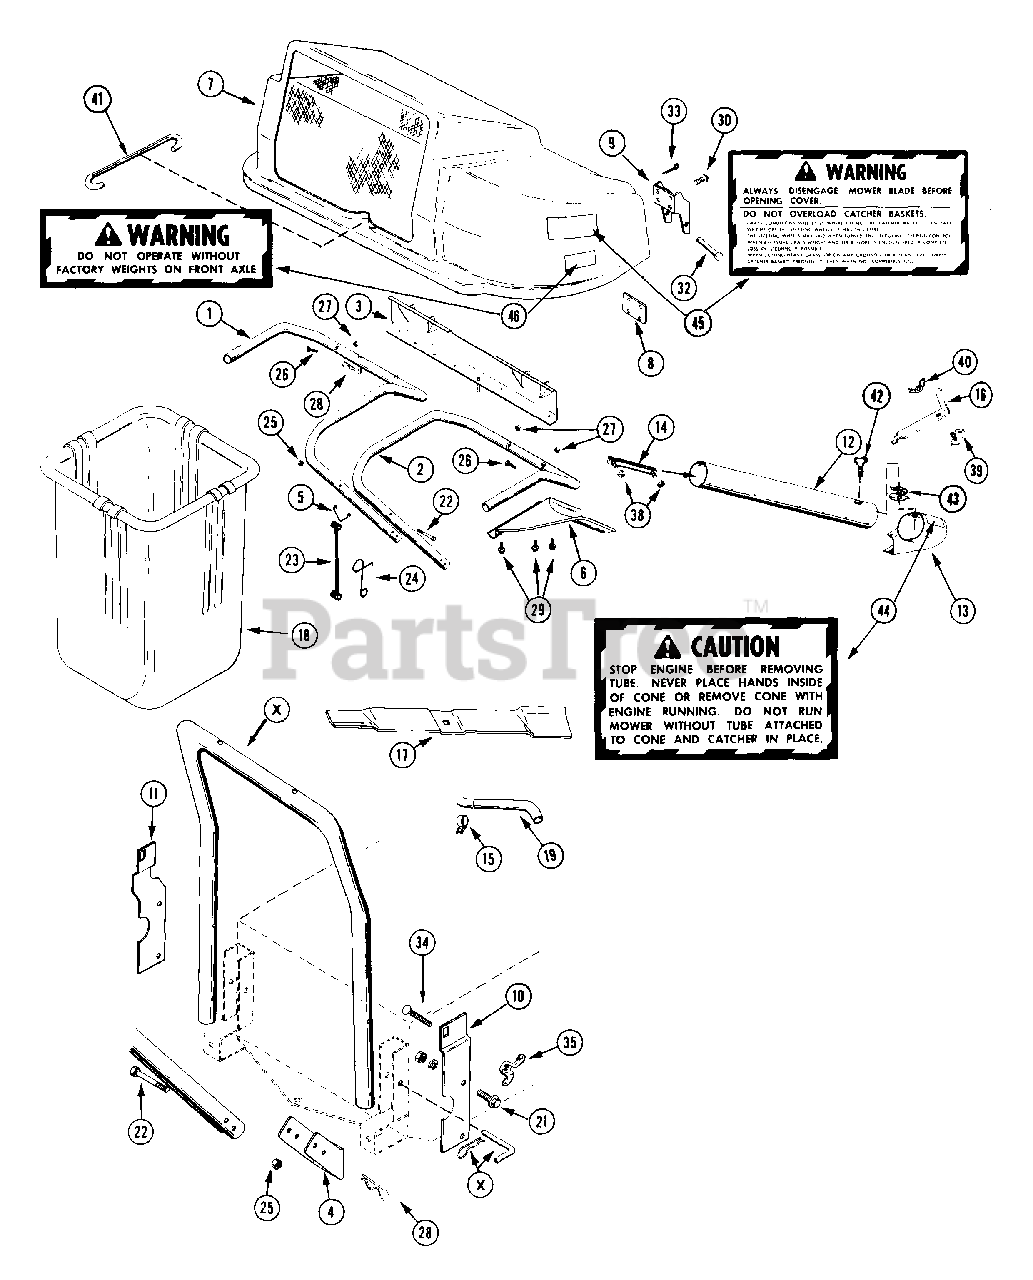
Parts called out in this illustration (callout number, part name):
1	TUBE L.H. SUPPORT
2	TUBE R.H. SUPPORT
3	FRAME-TUBE
4	BRACKET-MOUNTING
6	SUPPORT TUBE
7	GRASS CATCHER COVER ASSEMBLY
8	PLATE REINFORCEMENT
10	STABILIZER R.H.
11	STABILIZER L.H.
12	TUBE BLANK
13	GRASS CATCHER CONE ASSEMBLY
16	STRAP CONE
17	MOWER BLADE
19	EXHAUST PIPE EXTENSION
21	BLT-SERHFWH .31-18X.50 PL
22	BLT-HEX .25-20X2.50 PL GR2
23	BATTERY STRAP
24	HOOK
25	NUT-LK-CTR .250-20 PL
26	SCR-MCH .31-18X1.50 CROVCNTRS
27	NUT-LK-NYL.312-18 PL
28	PIN-HAIR INT .08X.38X1.42 YWZC
29	BLT-SERHFWH .25-20X.50 PL
30	BLT-SCRHFWH .25-20X.62 PL
32	CLEVIS PIN
33	PIN-COTR .06X.50
34	BLT-CRVD-HD .31-18X1.44 YWZC
35	WING NUT, .312-18
38	NUT-LK-FLG .250-20 PL
39	CLIP CONE
40	NUT-WING W/INSERT .312 - 18
41	WIRE HOOK
42	SCR-THUMB .31-18X.50 PL
43	NUT .375-24 PL
44	CAUTION DECAL
45	WARNING DECAL
46	WARNING DECAL
